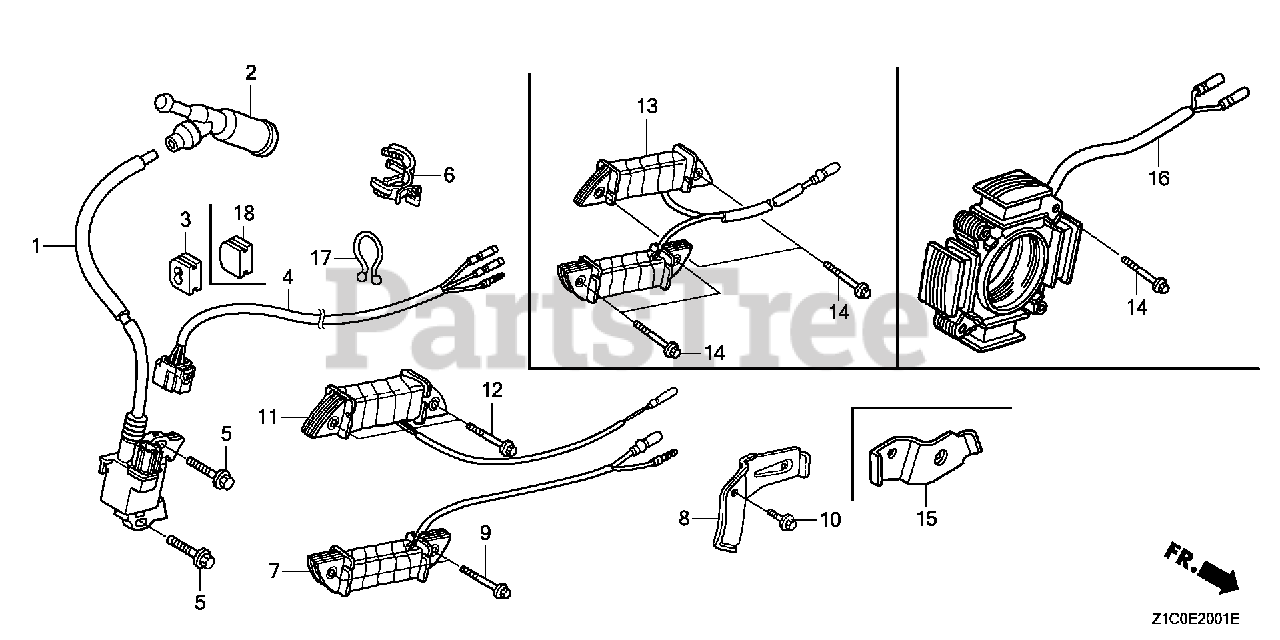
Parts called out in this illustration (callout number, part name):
1	COIL ASSY., IGNITION
1	COIL ASSY., IGNITION (IIDA)
2	CAP ASSY., NOISE SUPPRESSOR (NGK Y-EZD)
3	GROMMET, WIRE
4	WIRE HARNESS ASSY., ENGINE
5	BOLT, FLANGE (6X28) (CT200) Use up to Engine SN 1530314.
6	CLIP, WIRE HARNESS
